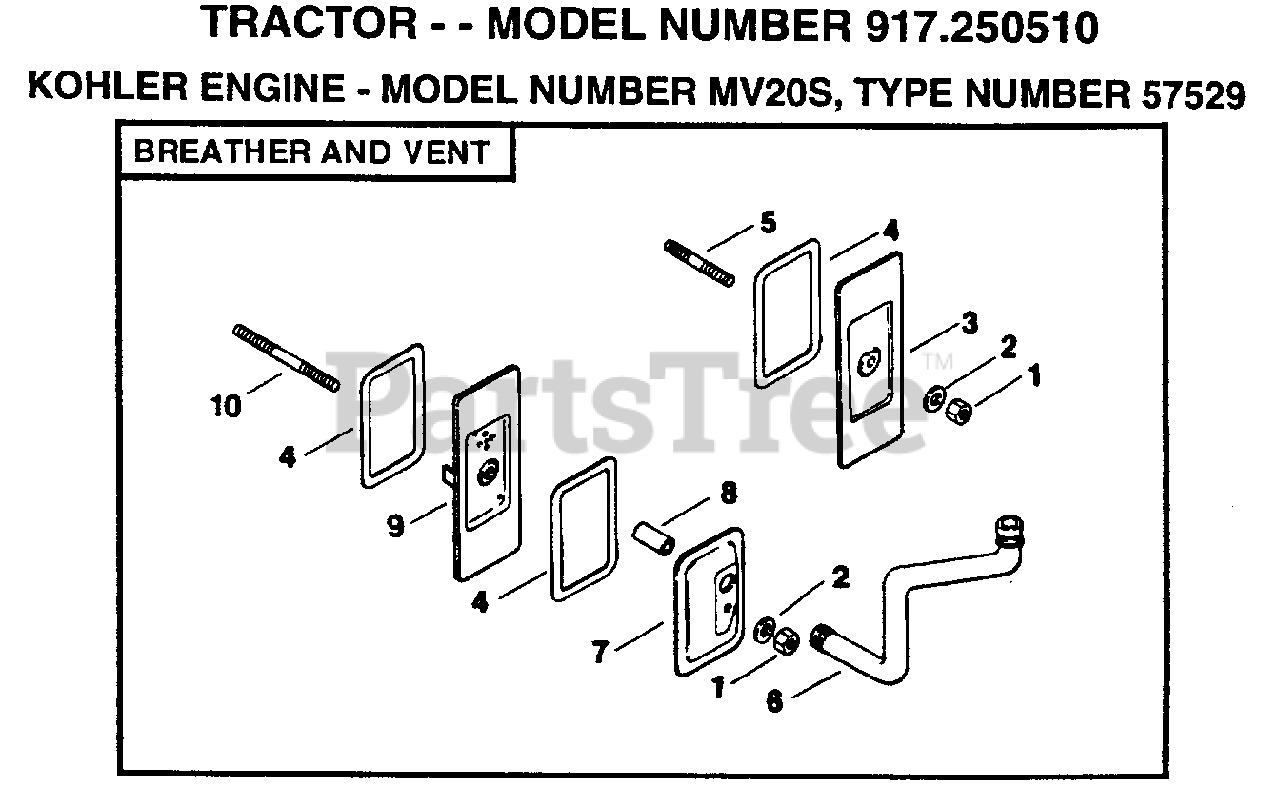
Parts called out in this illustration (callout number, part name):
1	NUT
2	WASHER
5	STUD
8	SEAL BREATHER
9	BREATHER ASSY
10	STUD
